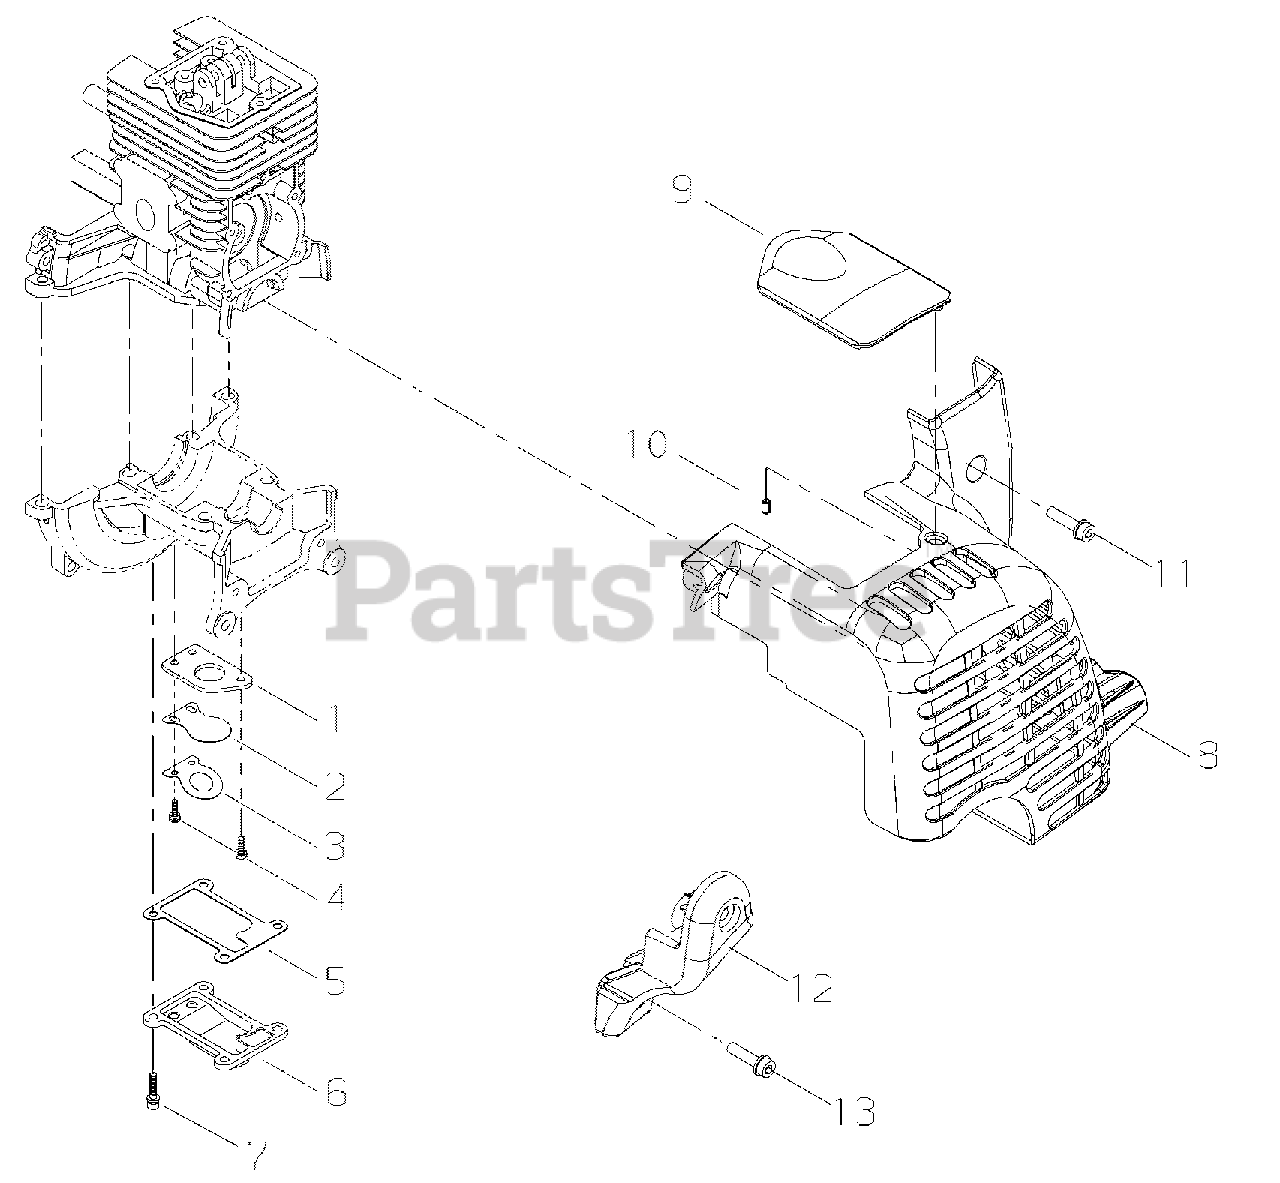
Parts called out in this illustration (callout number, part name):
1	PLATE, REED BACKING
2	VALVE, REED
3	STOP, REED VALVE
4	SCREW M3×10
5	GASKET, REED VALVE
6	COVER, REED VALVE
7	BOLT M4×12
8	COVER, ENGINE
9	COVER, SPARK PLUG
10	PIN, SPRING 4×8
11	BOLT M5×20
12	MOUNT, HANDLE
13	BOLT M5×20
